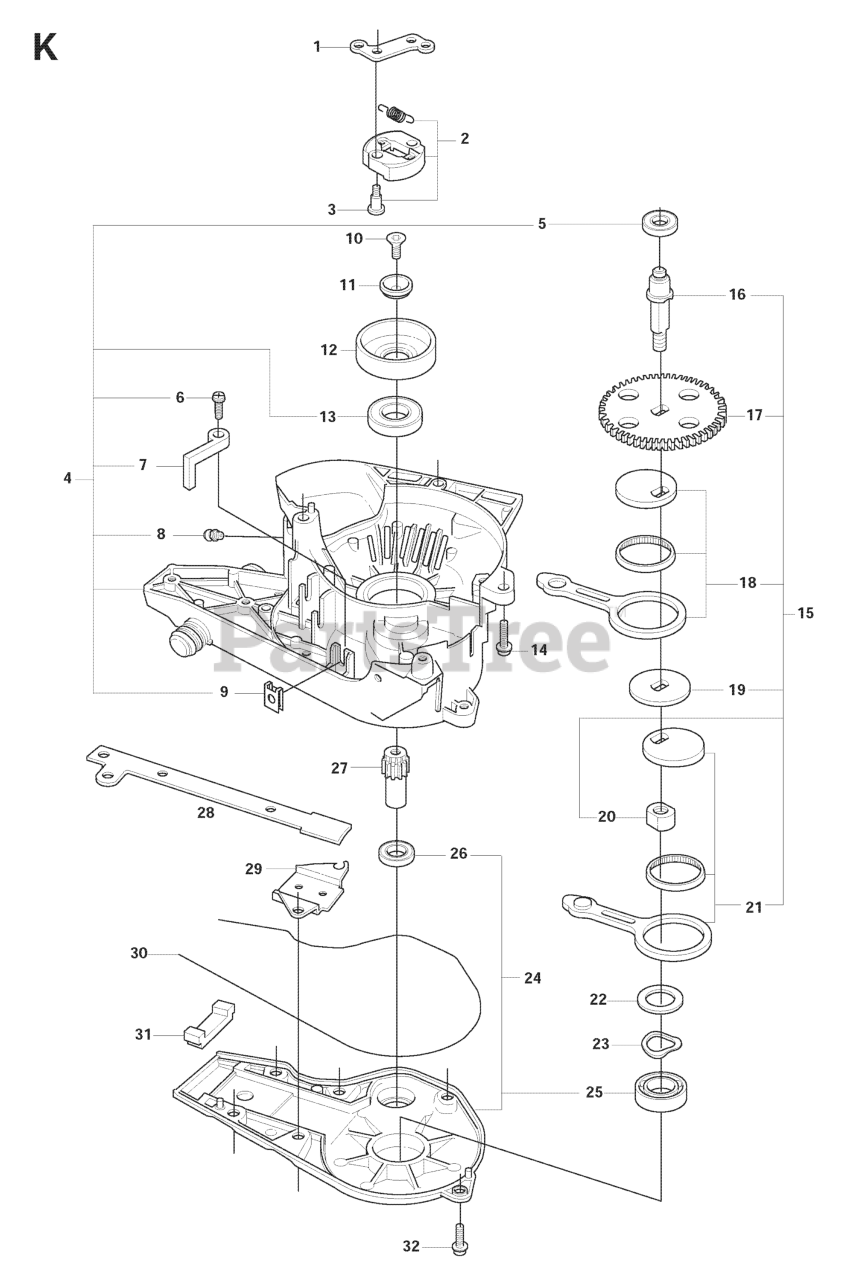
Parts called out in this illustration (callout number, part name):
1	CLUTCH YOKE
2	CLUTCH CPL
4	GEAR HOUSING
5	BALL BEARING
8	GREASE NIPPLE
12	CLUTCH DRUM
13	BALL BEARING 6002-2RS1
18	CONNECTING ROD
21	CONNECTING ROD
22	WASHER 15X24
